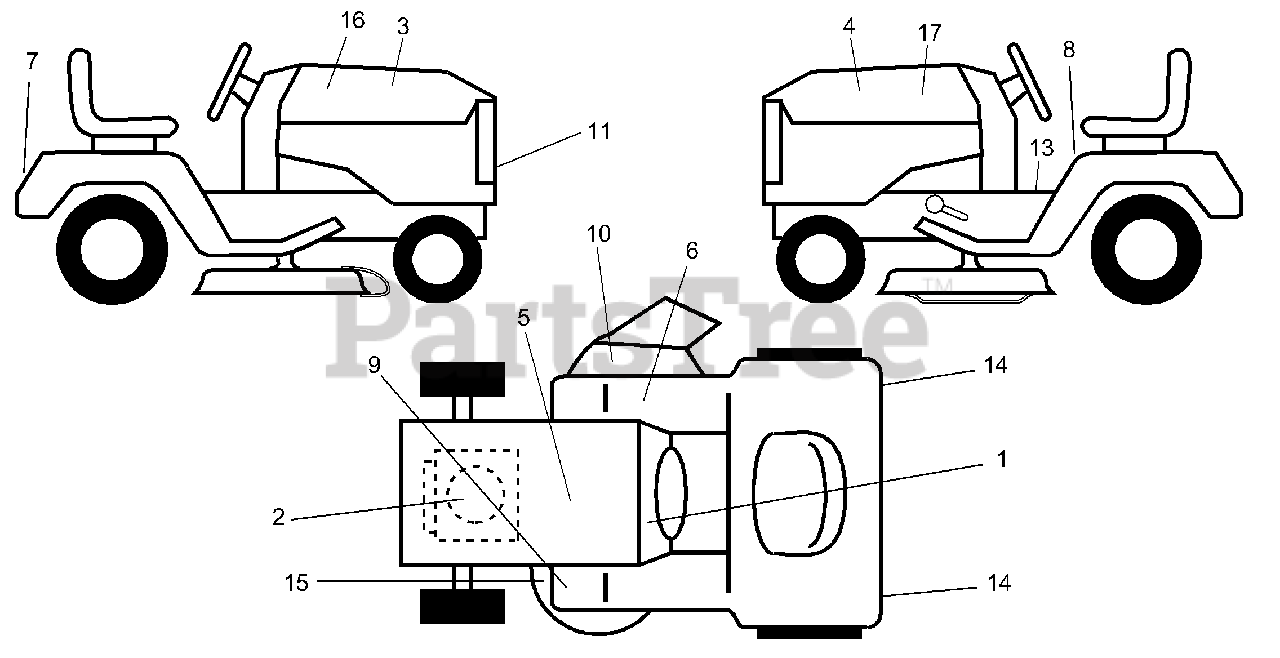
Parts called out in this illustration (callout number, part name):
1	Decal Instruction Dash Eng/fr
2	Decal HP Engine
3	Decal Hood RH Husq
4	Decal Hood LH Husq
5	Decal Bat Dan/Poi P/L Symbols
7	Decal Fender Husqvarna
8	Decal Caution Fender Eng/fr
9	Decal Clutch/brake Eng/fr
10	Decal Warning MULT-LANGUAGE
11	Decal Grille Husqvarna
13	Decal Brake Parking Saddle
14	Reflector Tail Light Red/amber
15	Decal V-Belt Mower Multi-Lang.
16	Decal Insert Hood Rh YT180 6 sp.
17	Decal Insert Hood Lh YT180 6sp.
